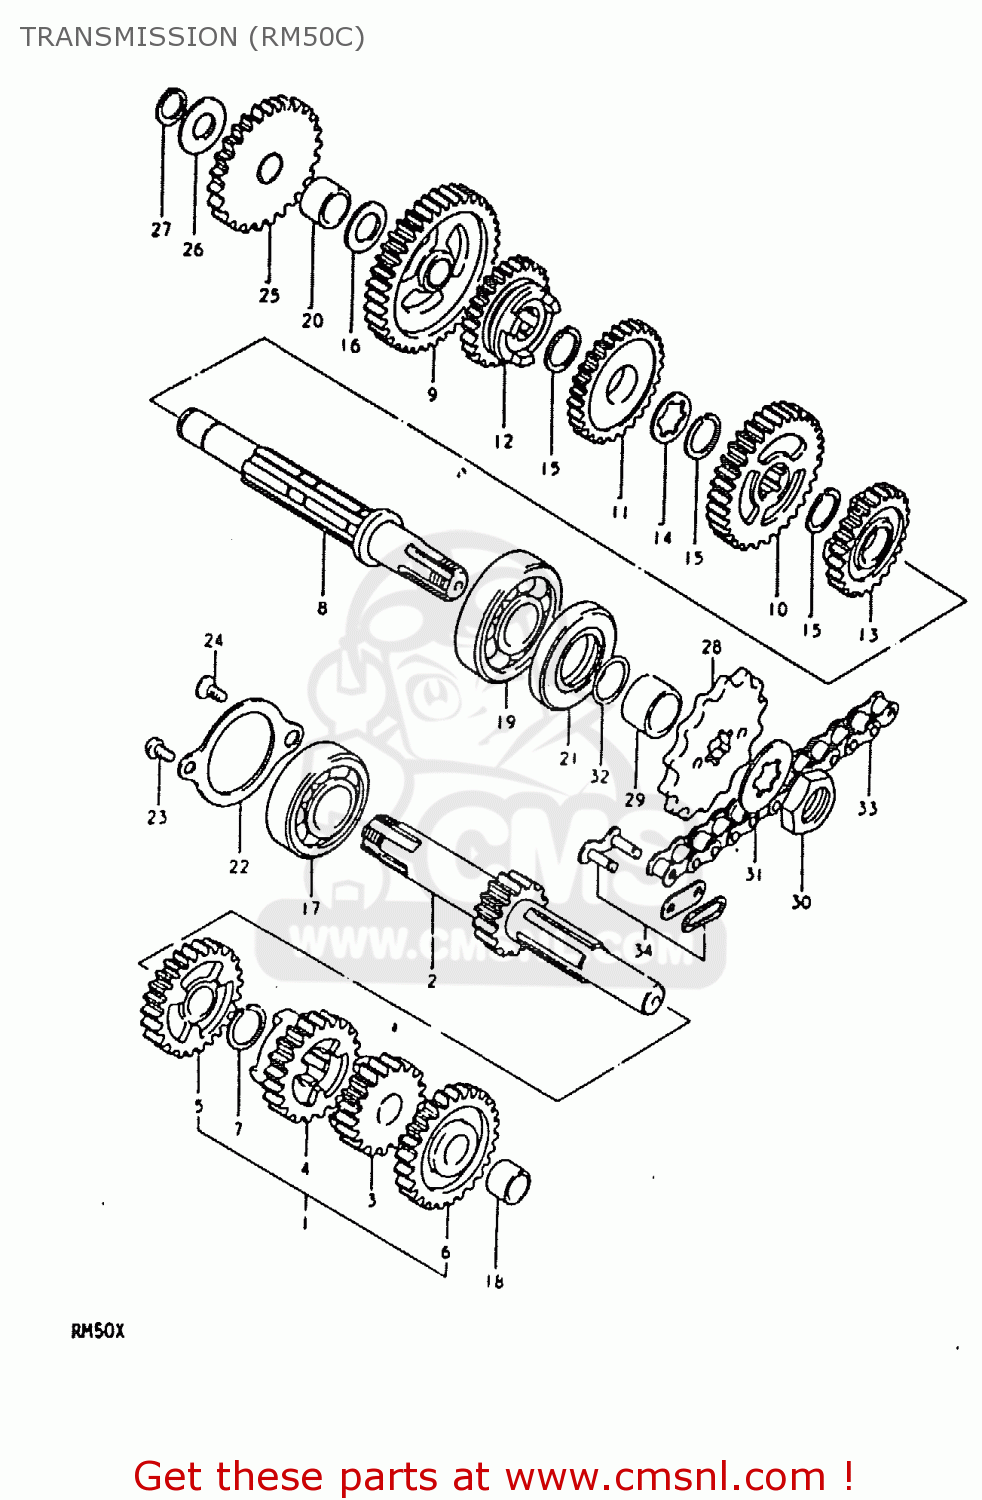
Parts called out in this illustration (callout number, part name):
1	SHAFT,COUNTER
2	SHAFT,COUNTER(NT:12)
3	GEAR,SECOND DRIVE
4	GEAR,THIRD DRIVE
5	GEAR,4TH DRIVE(NT:24)
6	GEAR,FIFTH DRIVE
7	CIRCLIP
8	SHAFT,DRIVE
9	GEAR,FIRST DRIVEN
10	GEAR,2ND DRIVEN(NT:33)
11	GEAR,3RD DRIVEN(NT:29)
12	GEAR,FOURTH DRIVEN
13	GEAR,5TH DRIVEN(NT:24)
14	WASHER(13X24X1)
15	CIRCLIP
16	WASHER,LOCK
17	BEARING
18	BUSH
19	BEARING
20	BUSH
21	SEAL,OIL(21X40X6)
22	RETAINER,CNTR SHAFT BEARING
23	SCREW
24	SCREW
25	GEAR,KICK STARTER IDLE
26	WASHER
27	CIRCLIP
28	SPROCKET,ENGINE(NT:12)
29	SPACER(17X21X13)
30	NUT
31	WASHER
32	O RING(D:1,ID:16.8)
33	CHAIN ASSEMBLY,DRIVE
34	JOINT ASSEMBLY,CHAIN
